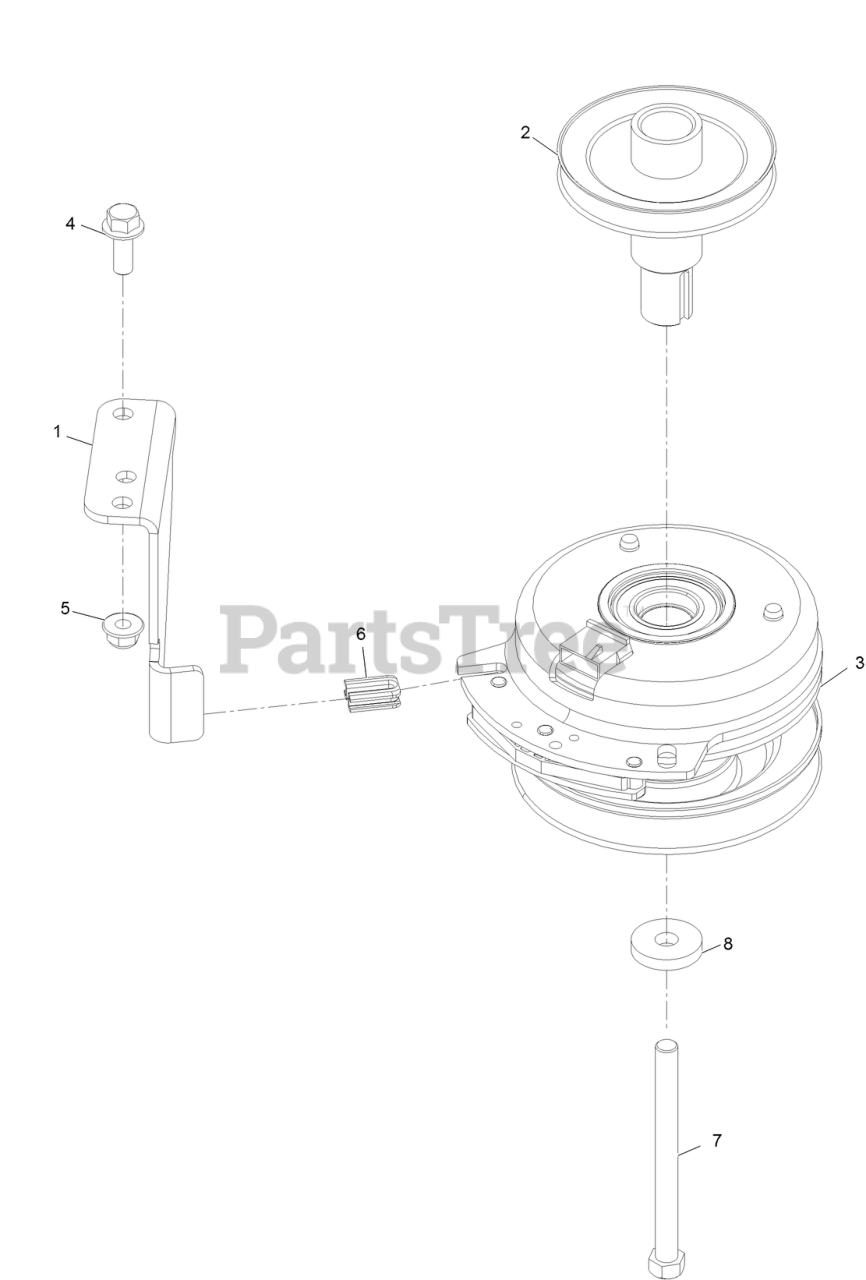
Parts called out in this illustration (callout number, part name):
1	STOP-CLUTCH (WIDE)
2	Pulley-Engine
3	CLUTCH-PTO
4	SCREW-HHF 3/8-16 X 1
5	NUT-HF, NI
6	ISOLATOR-CLUTCH
7	SCREW-HH
8	WASHER
